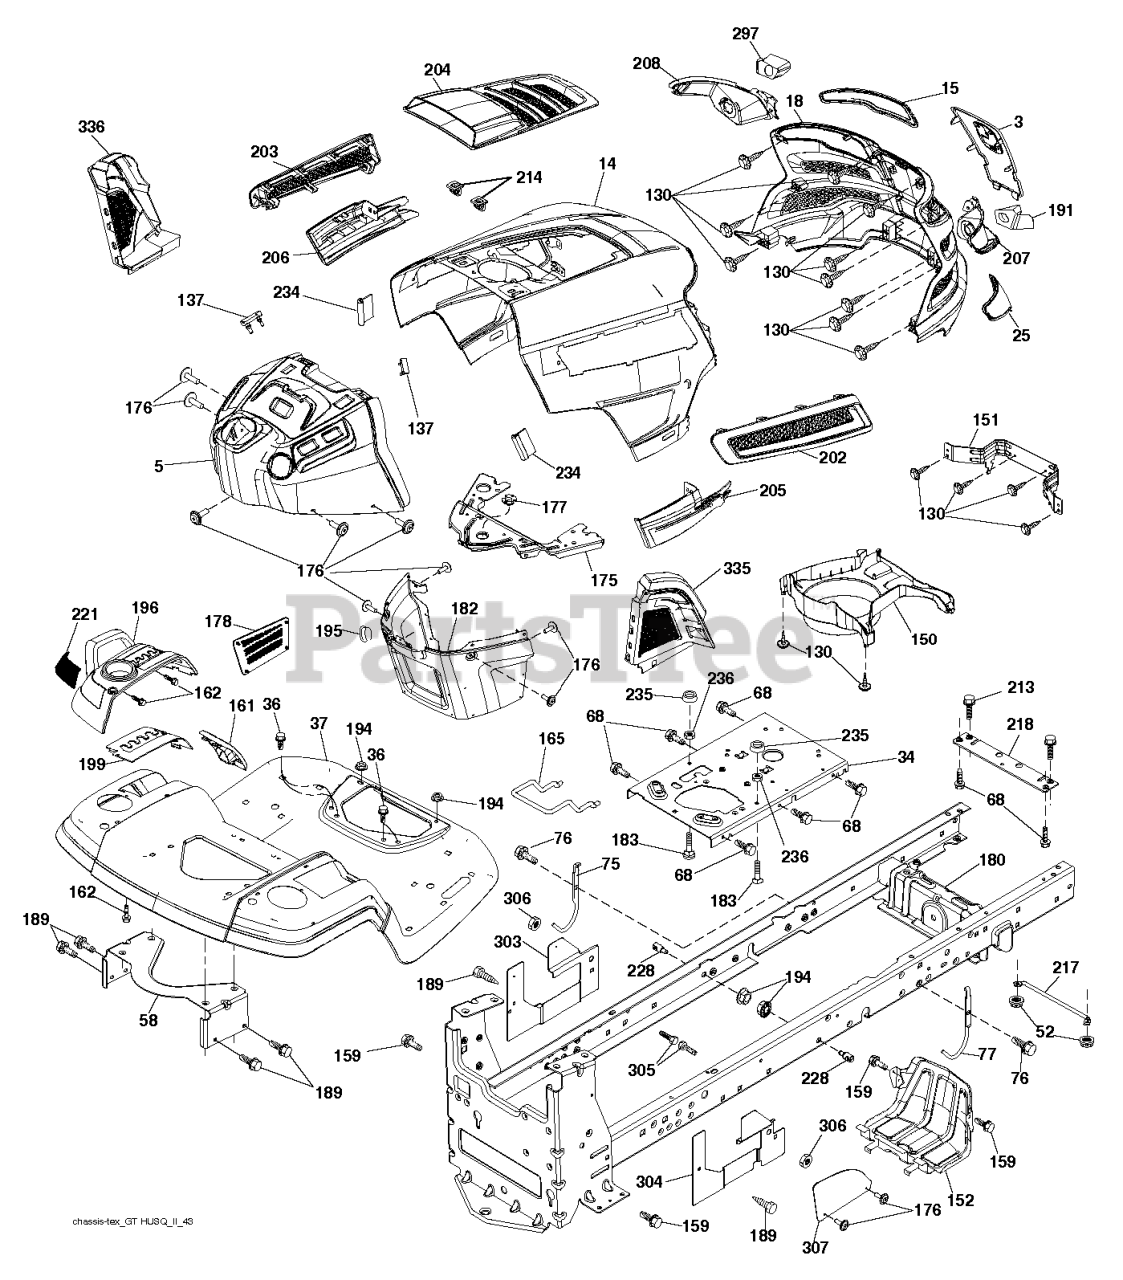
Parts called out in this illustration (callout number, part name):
3	APPLIQUE.SUBASM.GT.HUSQ.II
5	DASH.UPP.GT2.SM.PTO.MCHOKE
14	HOOD.ASM.HUSQVARNA.GT.TEX.ORAN
15	LENS.HEADLIGHT.LH.GTII.2011
18	GRILLE.SUBASM.GT.HUSQ.II
25	LENS.HEADLIGHT.RH.GTII.2011
34	PLATE.ENGINE.WELDED.CHASSIS
36	SCREW 5/16"
37	FENDER.PNT.TX.GT.CH/FW/DL.HUSQ
52	LOCKNUT
58	BRKT.SUPPORT.FNDR/TANK
68	SCREW LT
75	ROD UPSTOP
76	SCREW 3/8-16X1
77	ROD UPSTOP
130	SCREW.#10 X 0.750.BOS
137	BUMPER DASH
150	AIR.DUCT.GTV2(2.54"RING HEIGHT
151	BRACKET.PIVOT.HOOD.GT.HUSQ.II
152	SHIELD.BROWNING.PNT.GT.V2
159	SCREW, 3/8-16X3/4
161	CONSOLE.WINDOW.FUEL.HUSQ.GT
162	SCREW.HI-LO.CONSOLE
165	SUPPORT.TANK.REAR.W/TEX
175	PLATE.CROSSMEMBER.HUSQ
176	SCREW.#10-24X5/8.RN.QU
177	BUSHING, STEERING
178	CARGO.ASM.NET.TXGT.W/C
180	CHASSIS.GT.SLOPED.DRAWBAR.
182	DASH.LOWER.COMMON.12V.ADAPTOR
183	BOLT.5/16-18X1-1/4 FULL THD
189	SCREW
191	INSERT.REFLECTIVE.RH.HUSQ.GTII
194	NUT LOCK HEX FLANGE 5/16-18
195	PLUG.HOLE.DASH.LOWER.12V.BLK
196	SUBASM.CONSOLE.HUSQ.GT.DECKLFT
199	PLATE.DECK.LIFT.HUSQVARNA.GT
202	VENT.SIDE.RH.GT.HUSQ.II.
203	VENT.SIDE.LH.GT.HUSQ.II.498
204	VENT.TOP.HUSQ.GT2
205	SIDE.TRIM.RH.GT.HUSQ.II
206	SIDE.TRIM.LH.GT.HUSQ.II.GRAY
207	BEZEL LIGHT.RH.GT.II.MYLAR
208	BEZEL LIGHT.LH.GT.II.MYLAR
213	BOLT
214	CLIP.RETAINER.TINNER.
217	ROD.PIVOT.HOOD
218	X-PIECE.HOOD.STOP.NON/
221	REFLECTOR.LH.TEX GT HU
228	STUD.FASTNER.W/ANTI-ROTATE
234	BUMPER.HOOD.TEX.HUSQVARNA
235	SPACER FENDER
236	NUT.CENTERLOCK.5/16-
297	INSERT.REFLECTIVE.LH.HUSQ.GTII
303	SHIELD CHASSIS LEFT
304	SHIELD CHASSIS RIGHT
305	BOLT
306	NUT LOCK FLG 3/8-16 UNC
307	SHIELD UPPER PEDAL
335	COVER.RH.CLOSE.OUT.BLACK
336	COVER.LH.CLOSE.OUT
